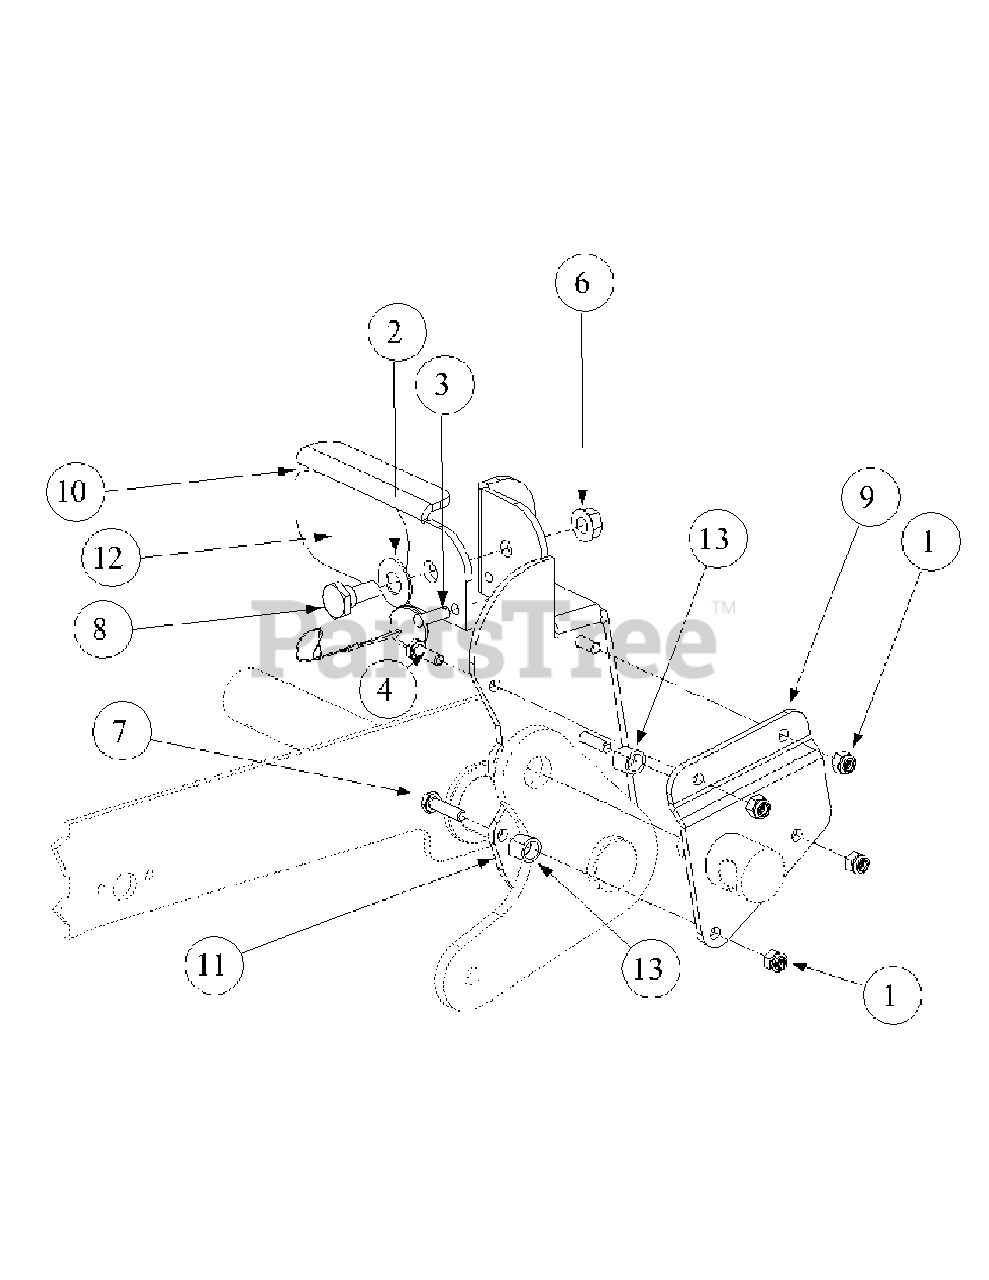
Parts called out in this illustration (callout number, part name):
1	Lock Nut, Nylon Insert, 1/4-20
2	Washer, 1/2 x 1 Shim
3	Detent Pin w/12" Lanyard
4	Hex Cap Screw, 1/4-20, .75
6	Hex Nut, Flange Lock 3/8-16
7	Hex Cap Screw, 1/4-20, 1.00
8	Shoulder Screw, .50 x .27 Lg., 3/8-16
9	Foot Lift Backup Pedal
10	Deck Foot Pedal Lift
11	Deck Foot Pedal Lift
12	Deck Foot Lift Pad
13	Turnbuckle Sleeve
